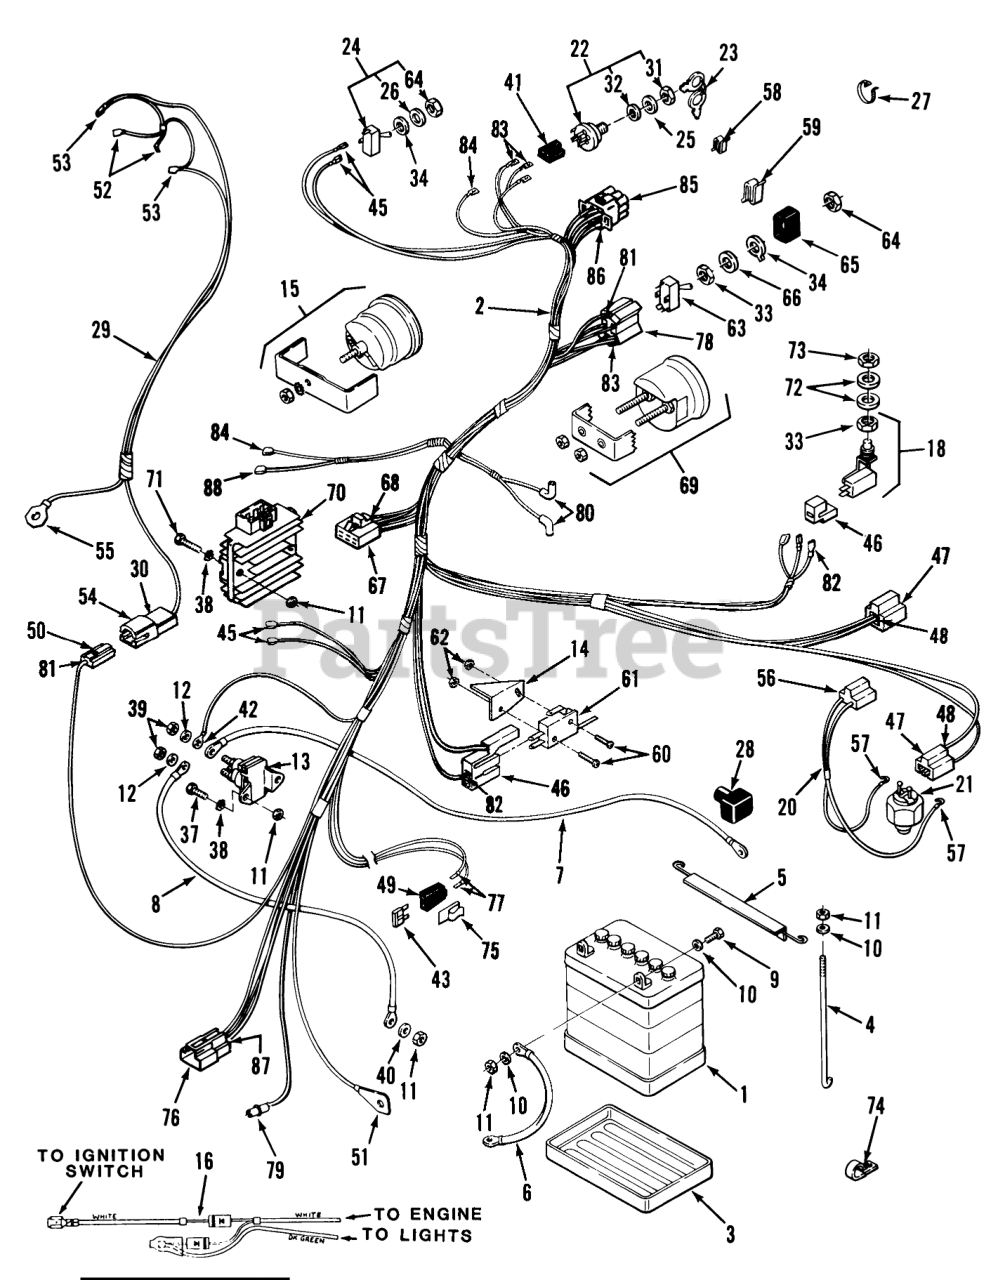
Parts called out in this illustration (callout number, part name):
1	Battery
2	WIRING-HARNESS & DIA
2	MAIN HARN & WIR DIAG
3	TRAY BATTERY
5	HOLDDOWN-BATTERY
6	WIRE -BLACK
7	WIRE - 14" BLACK
8	ASSY WIRE
9	Bolt
11	Nut
12	Washer
13	Solenoid (Includes two of item 11) 208-5 & 211-s.
14	Brake Switch Bracket
15	Hourmeter 212-6 Only (Includes 108768 clamp, 915538 #10-24 Nut & 920120 Ext. Tooth Lockwasher)
16	DIODE-KIT SERVICE
18	SWITCH-PUSH
20	ASSY WIRING HARNESS
21	SWITCH (N.C.-TRANS)
22	Ignition Switch (includes items 31 & 32)
